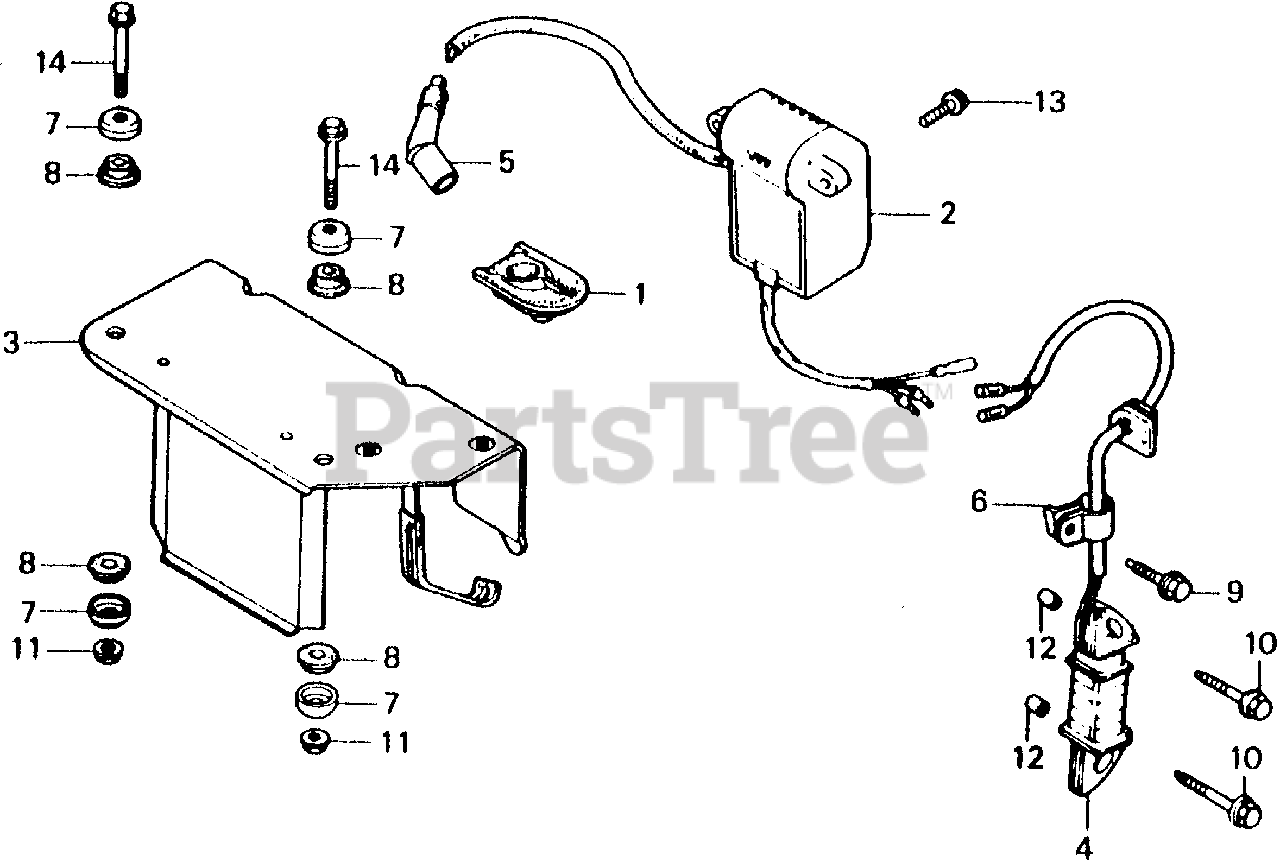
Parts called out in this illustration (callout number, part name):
1	GROMMET, SPARK PLUG
2	MODULE, IGNITION CONTROL (CDI)
3	BRACKET, IGNITION CONTROL MODULE
4	COIL ASSY., EXCITER
5	CAP ASSY., NOISE SUPPRESSOR
6	CLAMP, IGNITION WIRE
7	WASHER, INSULATOR (NOT AVAILABLE)
8	RUBBER, INSULATOR
9	BOLT, FLANGE (6X12) (CT200)
10	BOLT, FLANGE (6X28)
11	NUT, FLANGE (8MM)
12	PIN A, DOWEL (8X14)
13	BOLT, FLANGE (6X10)
14	BOLT, FLANGE (8X40)
